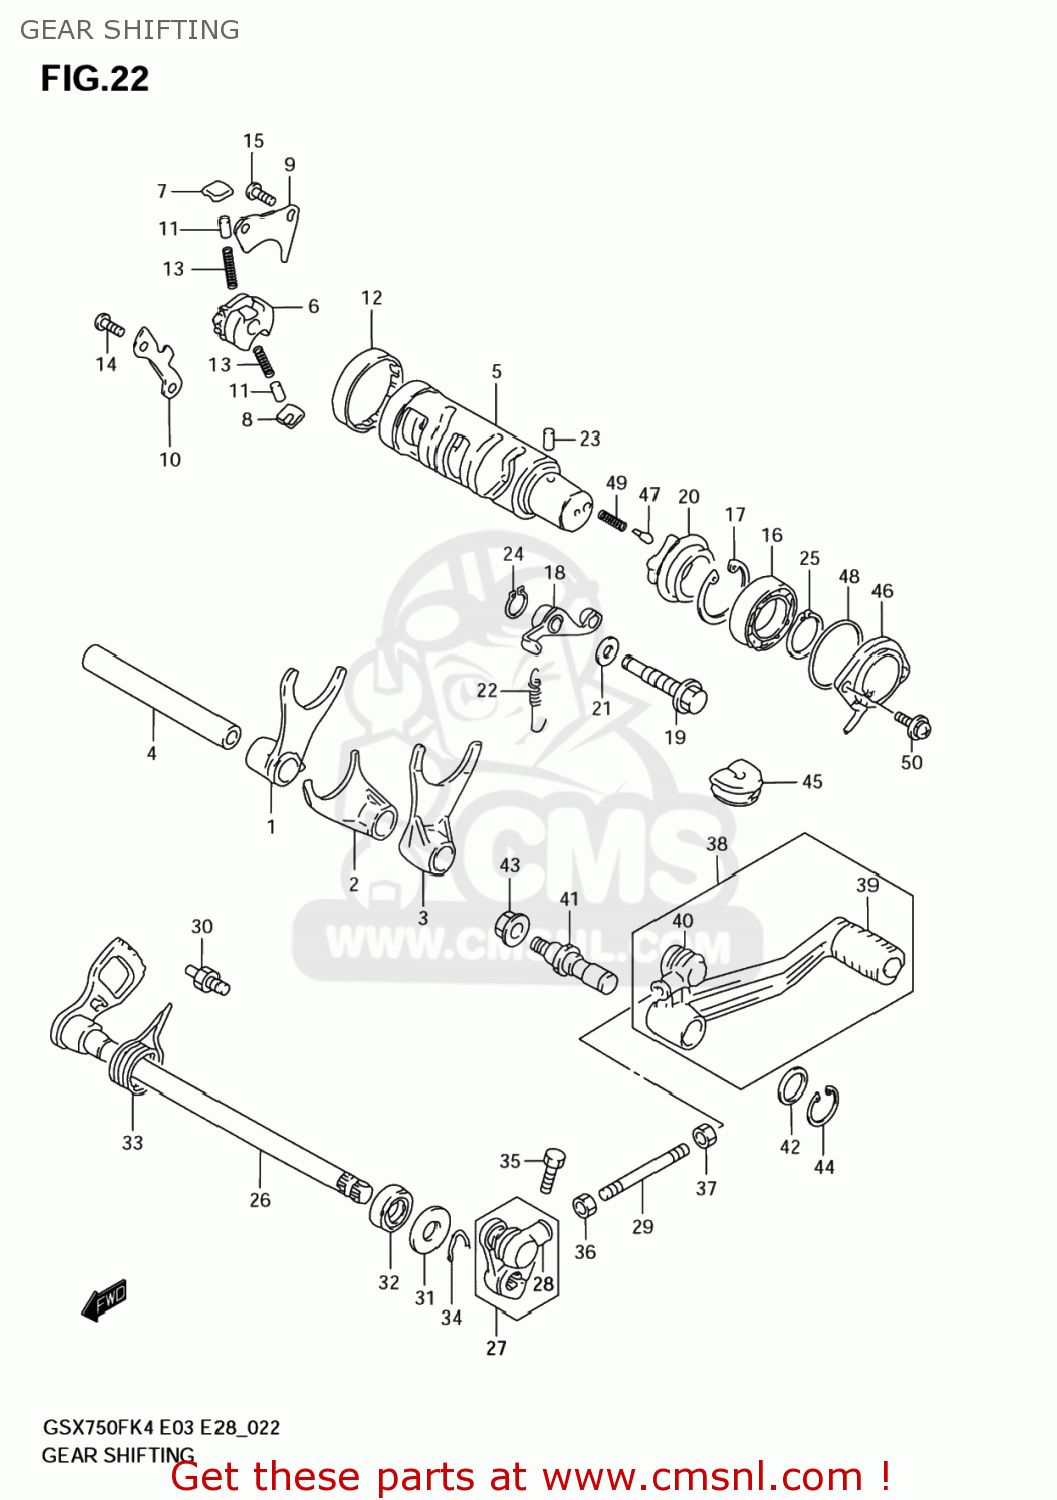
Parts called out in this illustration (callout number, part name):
1	FORK,GEAR SHIFT NO.1
2	FORK,GEAR SHIFT NO.2
3	FORK,GEAR SHIFT NO.3
4	SHAFT,GEAR SHIFT FORK(L:128)
5	CAM,GEAR SHIFT
6	GEAR,GEAR SHIFT CAM DRIVEN
7	PAWL,GEAR SHIFT NO.1
8	PAWL,GEAR SHIFT NO.2
9	LIFTER,GEAR SHIFT PAWL
10	GUIDE,GEAR SHIFT CAM
11	PIN(5X8)
12	BEARING(43X49X12)
13	SPRING
14	SCREW(6X12)
15	SCREW(6X12)
16	BEARING
17	CIRCLIP
18	STOPPER,GEAR SHIFT CAM
19	SHAFT,GEAR SHIFT CAM STOPPER
20	PLATE,STOPPER
21	GASKET(10X14X3.6) (NAS)
22	SPRING
23	PIN
24	CIRCLIP
25	CIRCLIP
26	SHAFT,GEAR SHIFT
27	ARM,GEAR SHIFT LINK
28	COVER,DUST
29	ROD,GEAR SHIFT LINK
30	STOPPER,GEAR SHIFT ARM
31	WASHER (12.5X26X1.6)
32	OIL SEAL
33	SPRING
34	CIRCLIP,12 MM
35	BOLT
36	NUT
37	NUT
38	LEVER ASSY,GEAR SHIFT
39	RUBBER,GEAR SHIFT PEDAL
40	COVER,DUST
41	SHAFT,GEAR SHIFT LEVER
42	WASHER(12.5X20X1)
43	NUT
44	CIRCLIP,12 MM
45	GROMMET,LEADWIRE
46	BASE ASSY,GEAR SHIFT TERMINAL
47	PIN(5X15.5)
48	O RING(D:2.4,ID:35.5)
49	SPRING
50	SCREW(5X16)
